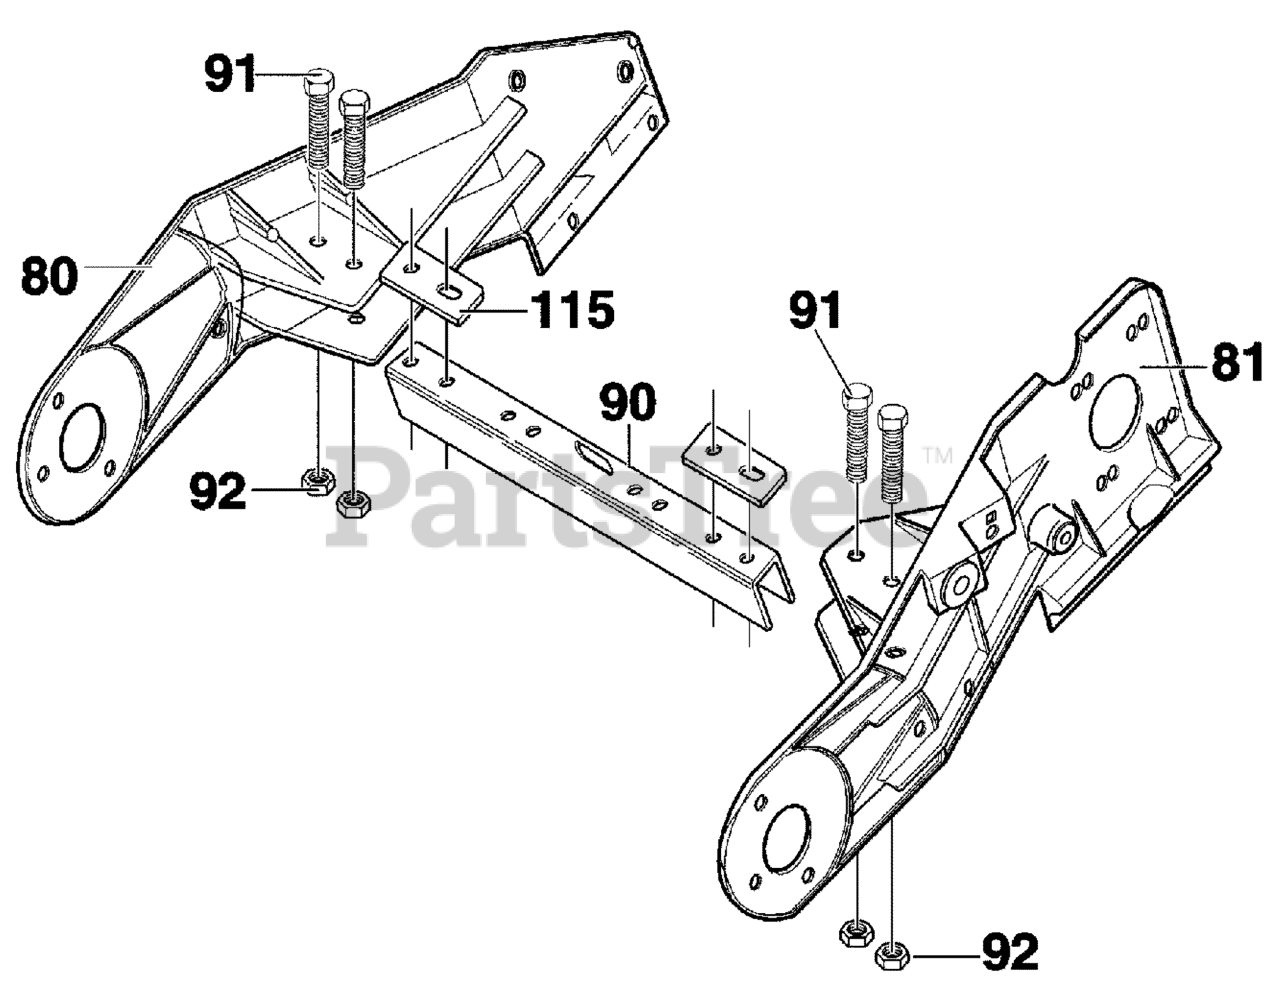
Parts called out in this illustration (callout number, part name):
80	FRAME, SIDE RH
81	FRAME, SIDE LH
90	CHANNEL SUPPORT
91	SCREW, 1/4-20 x 2.00
92	NUT, 1/4-20
115	PLATE, BOLTING SUPPORT
